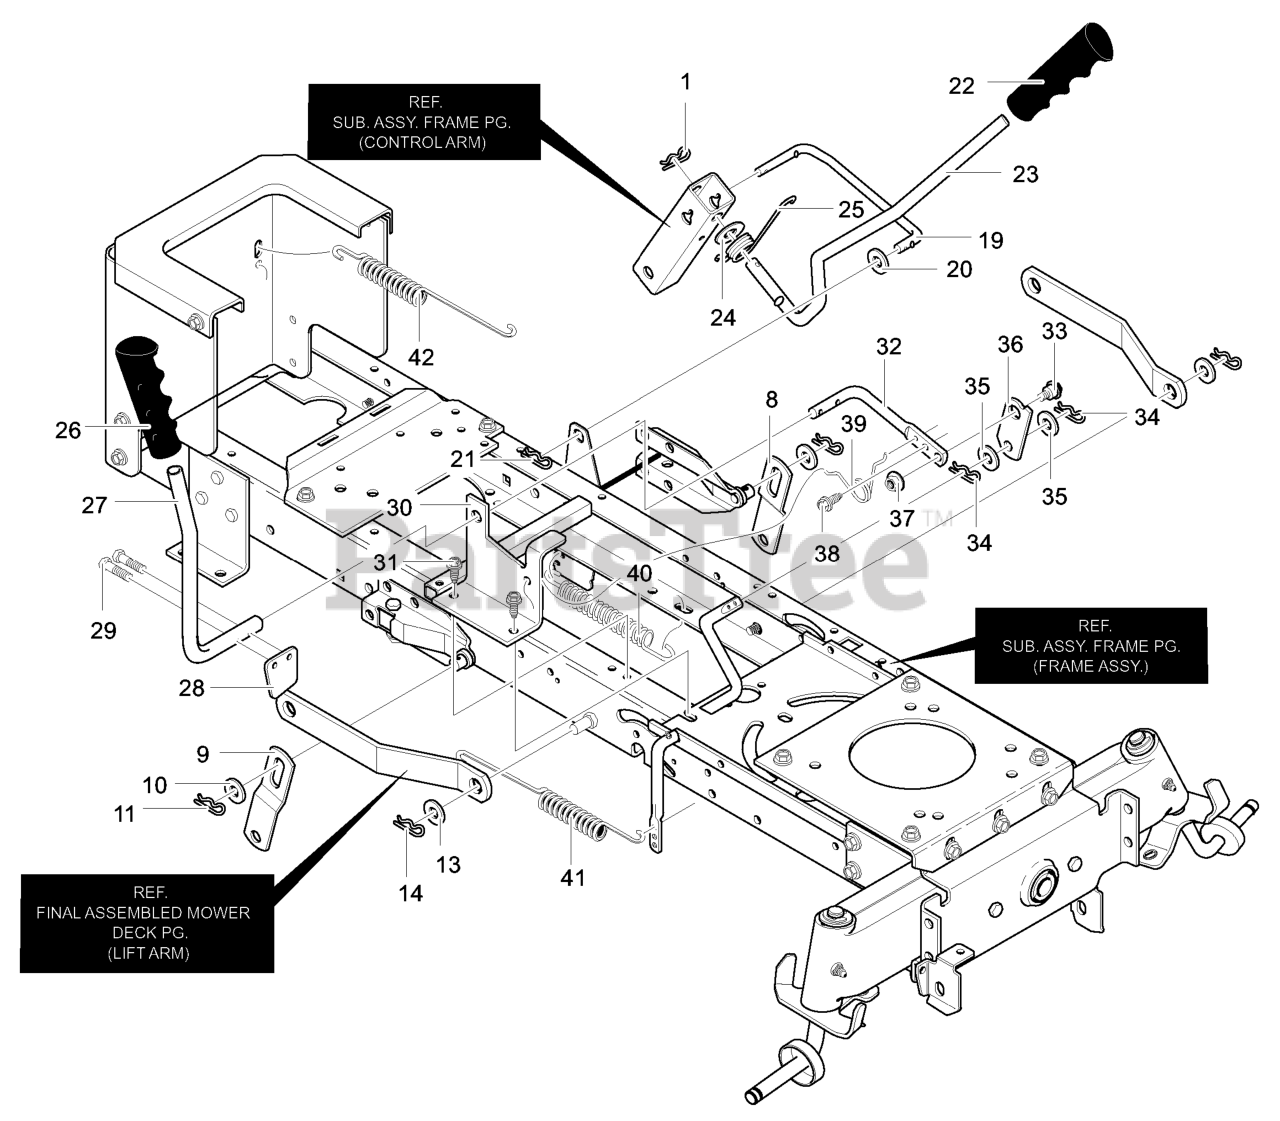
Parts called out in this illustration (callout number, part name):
1	PIN, HAIR
8	LINK, LIFT LH
9	LINK, LIFT RH
10	WASHER, FLAT
11	PIN, HAIR
13	WASHER, FLAT
14	PIN, HAIR
19	LINK LIFT HANDLE
20	WASHER, FLAT
21	PIN, HAIR
22	GRIP, DLX GREY
23	HANDLE, LIFT
24	WASHER, FLAT
25	TORSION SPRING
26	GRIP, PTO DLX GREY
27	PTO HANDLE H26
28	PADDLE, SWITCH
30	BRACKET, PTO
31	SCREW 5/16-18X.50
32	LEVER, PTO
34	PIN, HAIR
35	WASH, FLAT
36	LINK PTO
37	NUT, 3/8-16
38	SCREW 5/16-18X.75
39	TORISON SPRING
40	SPRING, EXTENSION
41	SPRING, EXTENSION
42	SPRING, EXTENSION
